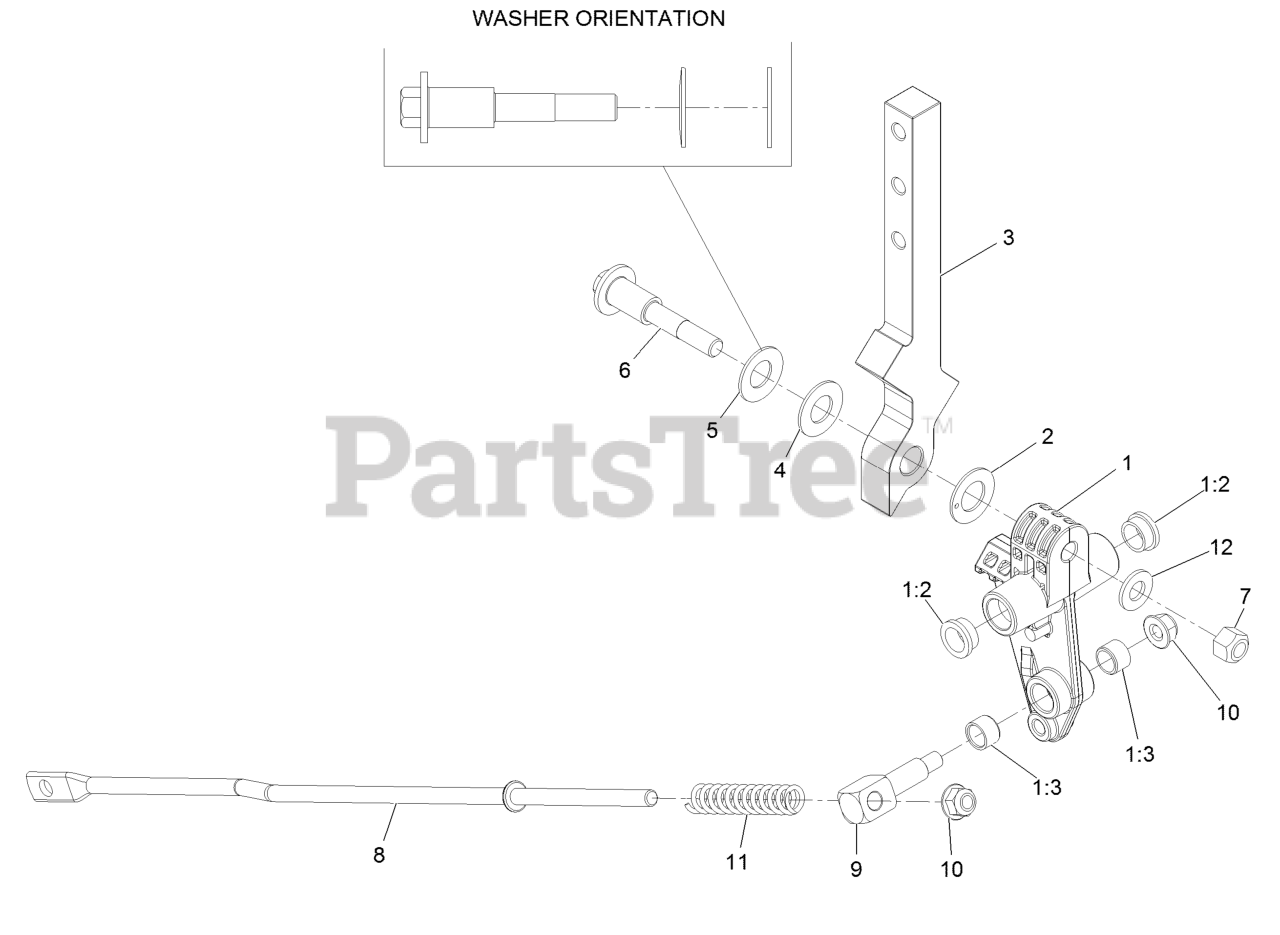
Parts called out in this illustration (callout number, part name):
1	Control Arm ASM
1:2	Bushing
1:3	Bushing-Sleeve
2	Washer-Friction
3	Arm-Control
5	Washer-Belleville
6	Bolt-Pivot
7	Nut-Hex 3/8-16 Lock
8	Link-Control
10	Nut-Nyloc 5/16-18 Flg
11	Spring-Return, Neutral
12	Washer-3/8 SAE
